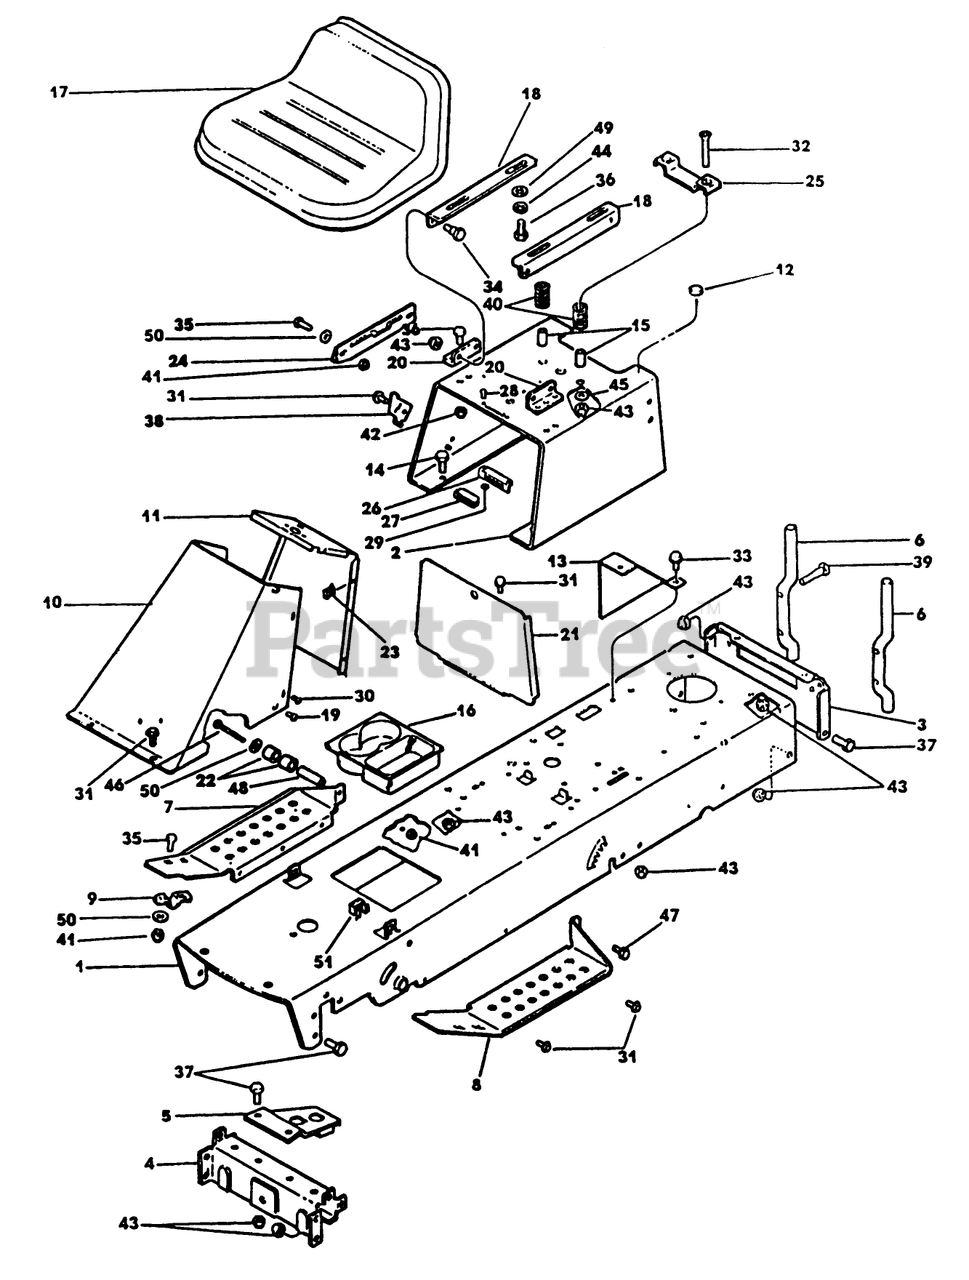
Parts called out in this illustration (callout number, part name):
5	STEERING BRKT WA*G
11	STEERING TOWER W/D(12)
12	BUMBER - SEAT
22	SPACER - RUBBER
31	SCREW-THREAD FRMG
33	SCREW-HWH
35	SCREW
36	SCREW - HEX
38	PLATE, LOCK* G
40	SPRING
41	NUT-LOCK, CONE
42	NUT
43	NUT-LOCKING
45	WASHER
